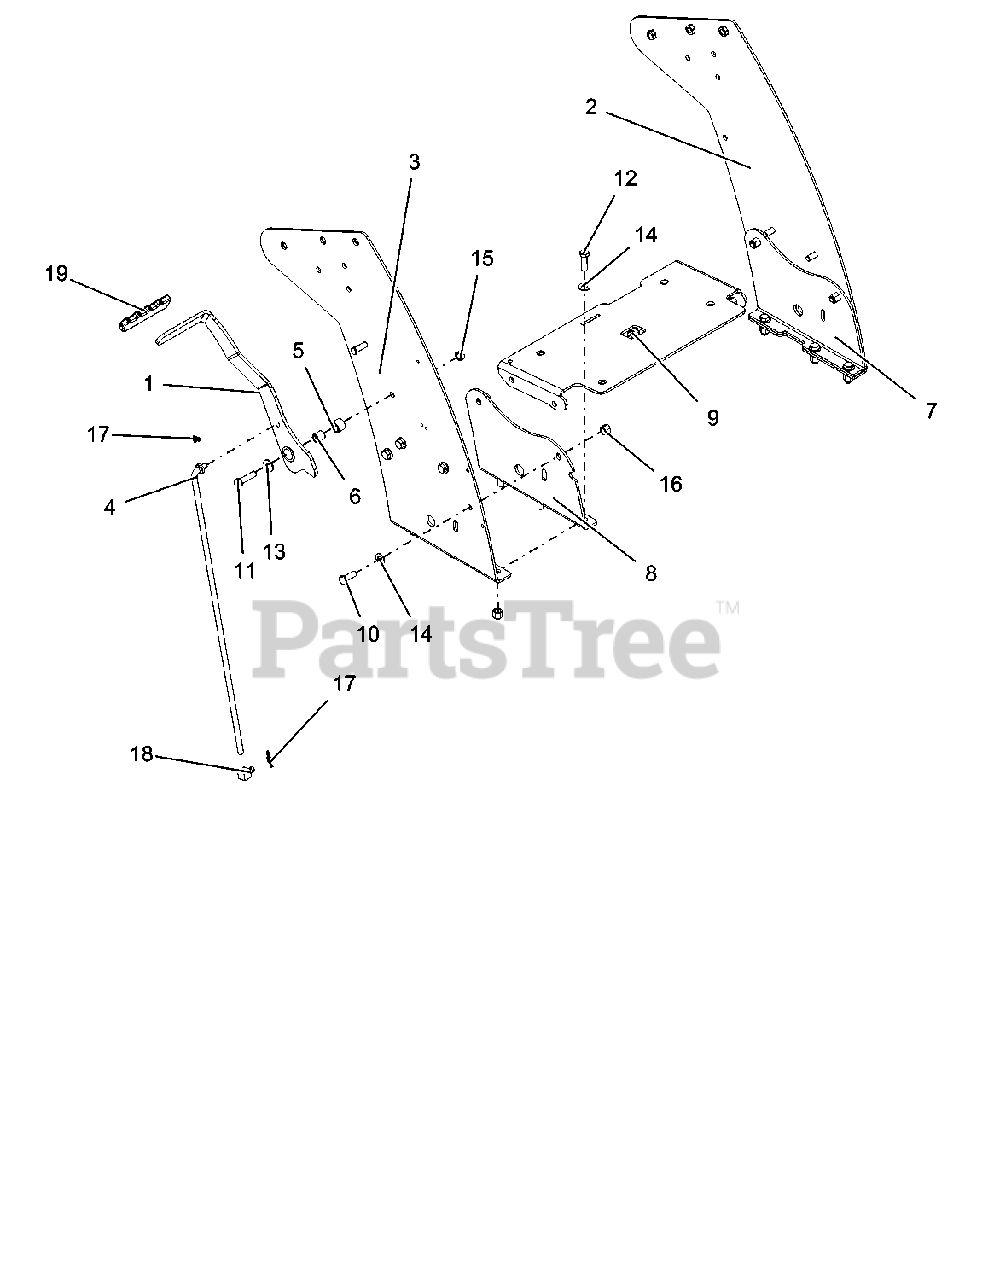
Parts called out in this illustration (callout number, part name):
1	PARK BRAKE WLDT-BLACK
2	WLDMT, LH UPRIGHT 18" ENG BED-RED
3	WLDMT, RH UPRIGHT 18" ENG BED-RED
4	ROD, DRIVE CONTROL FW
5	PARK BRAKE HANDLE BUSHING
6	PARK, BRAKE LEVER SPACER
7	PLATE, LH DOUBLER 36" UPRIGHT-RED
8	PLATE, RH DOUBLER 36" UPRIGHT (RED)
9	BRKT, FUEL TANK GRAVELY
10	BLT-HEX .38-16X1.00 GR5 YWZC
11	BLT-HEX .38-16X1.50 GR5 YWZC
12	BLT-HEX .38-16X1.25 GR5 YWZC
13	WSHR-FL-STL.38X.875X.083 YWZC
14	WSHR-FL-STL.406X.812X.065 YWZ
15	NUT-LK-CTR .38-16 YWZC
16	NUT-LK-NYL .38-16 YWZC
17	RING, RUE .375 x .054 x 1.254
18	SWIVEL, 3/8-24
19	GRIP
